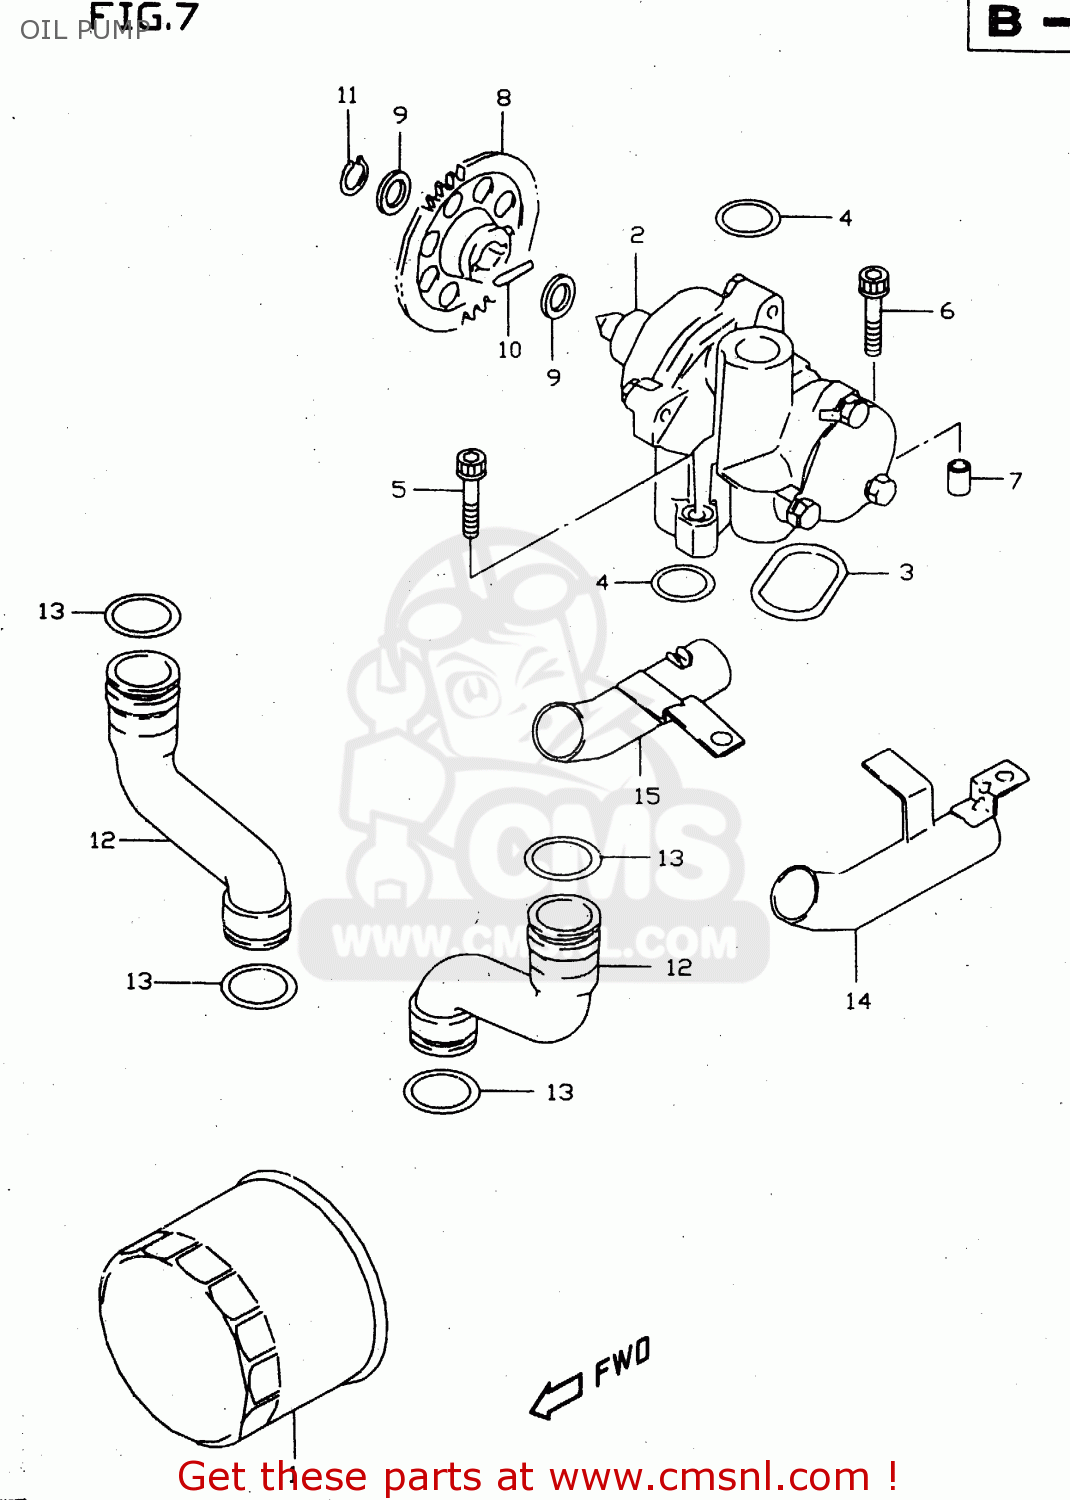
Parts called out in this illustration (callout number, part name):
1	FILTER ASSEMBLY,ENGINE OIL
2	PUMP ASSY,OIL
3	O RING,OIL PUMP
4	O RING(D:3.2,ID:17.8)
5	BOLT
6	BOLT
7	PIN
8	GEAR,OIL PUMP DRIVEN(NT:37)
9	SHIM
10	PIN(5X18)
11	CIRCLIP,12 MM
12	PIPE,OIL OUTLET
13	O RING(D:3.7,ID:21.7)
14	PIPE,OIL OUTLET UNDER,L
15	PIPE,OIL OUTLET UNDER,R
